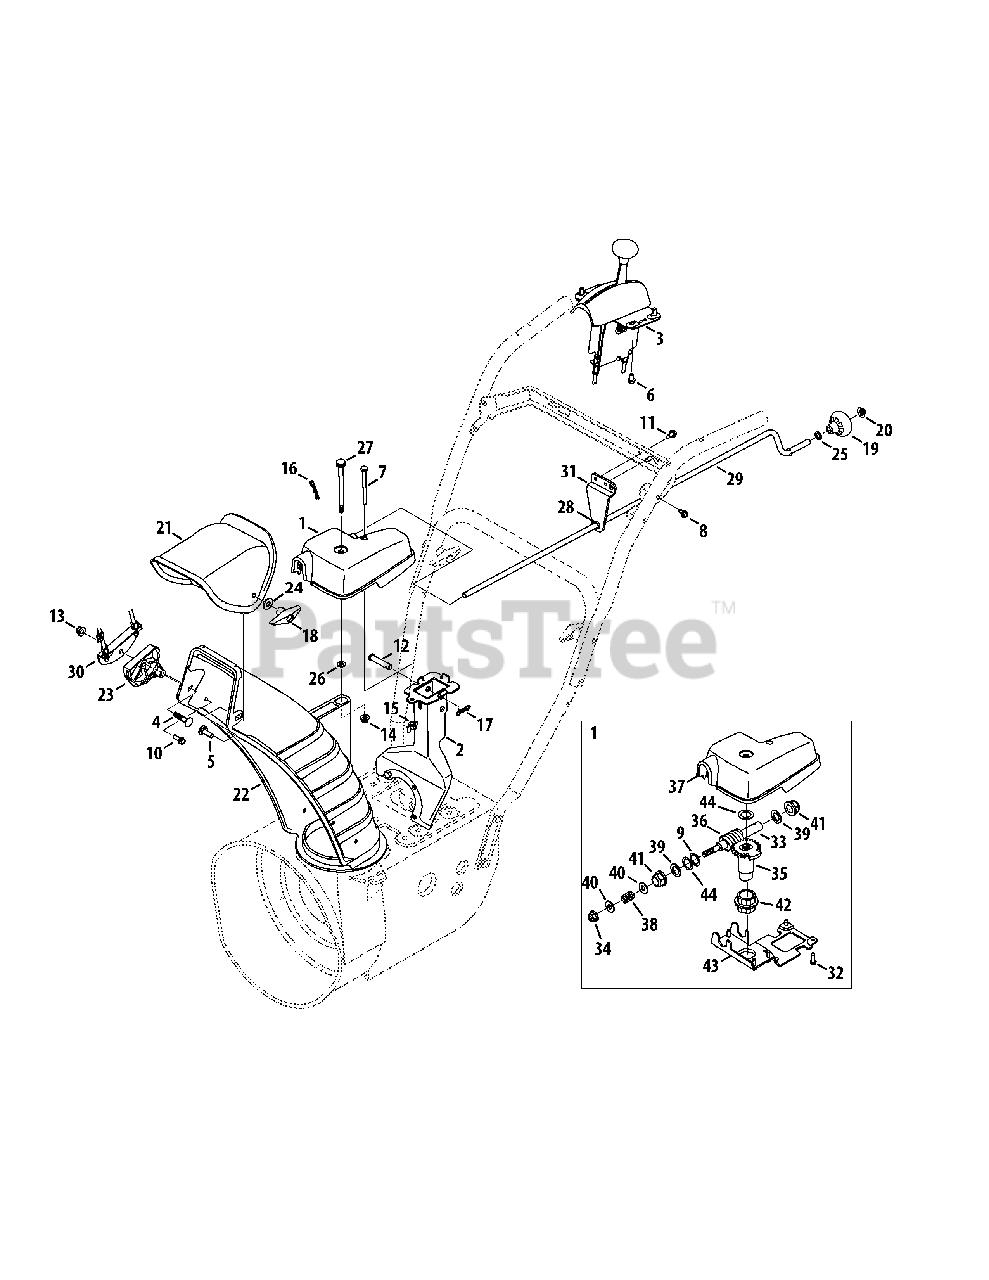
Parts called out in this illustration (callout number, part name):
1	Chute Rotation Gearbox
2	Chute Support Bracket
3	Chute Control, 2-Way
4	Bolt, Carriage, 5/16-18 x 1.50
5	Bolt, Carrier, 5/16-18 x 1.00
6	Screw, Hi-Lo, 1/4-15 x 0.50
7	Hex Head Screw, 1/4-20 x 3.00
8	Screw, TT, 1/4-20 x .500
9	Shim Washer, .632 x 1.00 x .010
10	Screw, Hi-Lo, 1/4-15 x 0.750
11	Screw, 1/4-20 x .625
12	Clevis Pin, 3/8 x 1.87
13	Nut, Flange Lock, 5/16-18
14	Nut, Flange Lock, 1/4-20
15	Wing Nut, 1/4-20
16	Internal Cotter Pin
17	Bow-Tie Cotter Pin
18	Wing Knob, 5/16-18
19	Shift Knob, .390
20	Push Cap, 3/8
21	Upper Chute
22	Lower Chute, 5.0
23	Cable Guide, Chute Tilt
24	Washer, Flat, .349 x .879
25	Flat Washer, .375 x .738 x .063
26	Washer, Flat, .25 x .630
27	Shoulder Screw, .312 x 3.5 x 1/4-20
28	Plastic Bushing, .380 ID
29	Chute Crank
30	Cable Bracket
31	Support Rod Bracket
32	Screw, 12-16 x .75
34	Flange Lock Nut, 3/8-16
35	Gear Assembly
36	Worm
38	Compression Spring, .39 x .60 x .88
39	Flat Washer, .625 x 1.0 x .067
40	Flat Washer, .380 x .93 x .110
41	Hex Bearing
42	Flange Bearing
44	Shim Washer, .63 x 1.00 x .020
